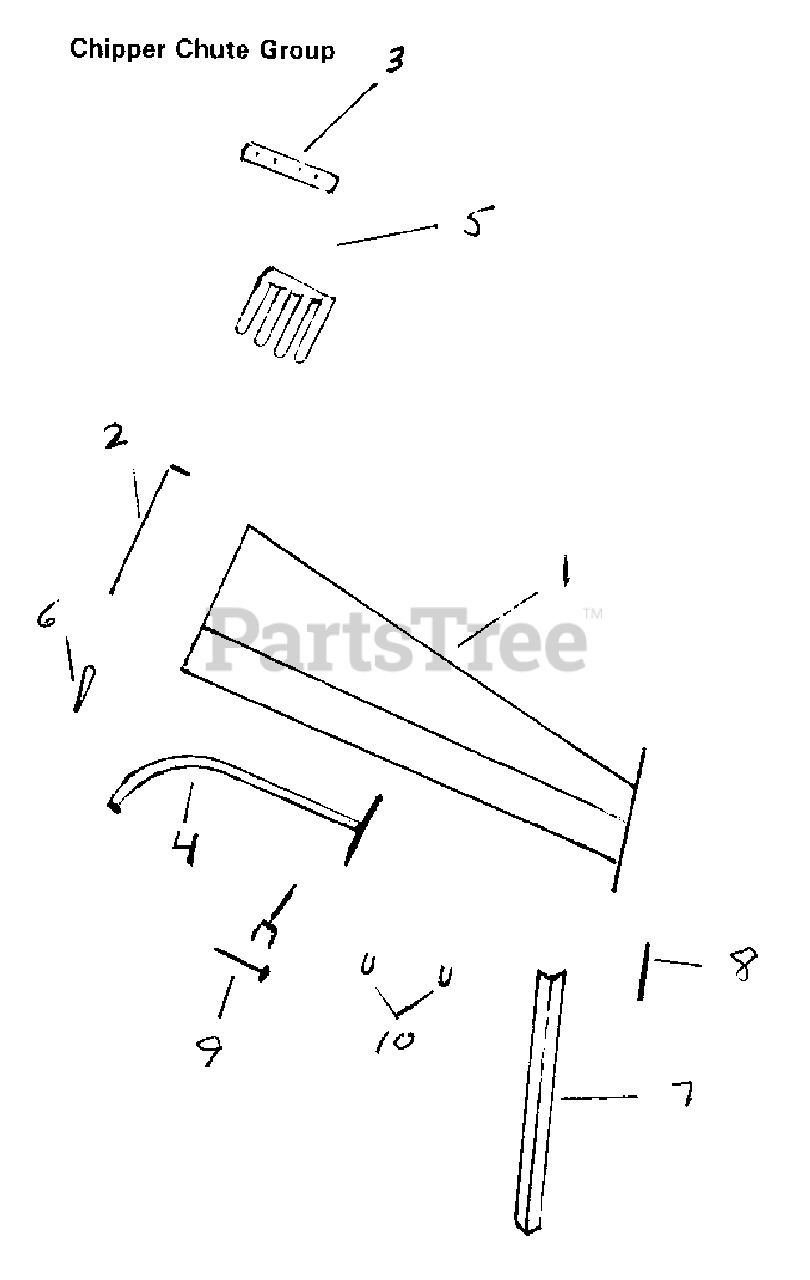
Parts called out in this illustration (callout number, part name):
1	Chipper Chute
2	Chipper Chute Door
3	Chipper Door Hinge
4	Chipper Chute Plunger
5	Rubber Deflector Flap
6	Rubber Tie Down
7	Chute Support
8	Bed Knife
9	Safety Holder
10	Plunger Holder
